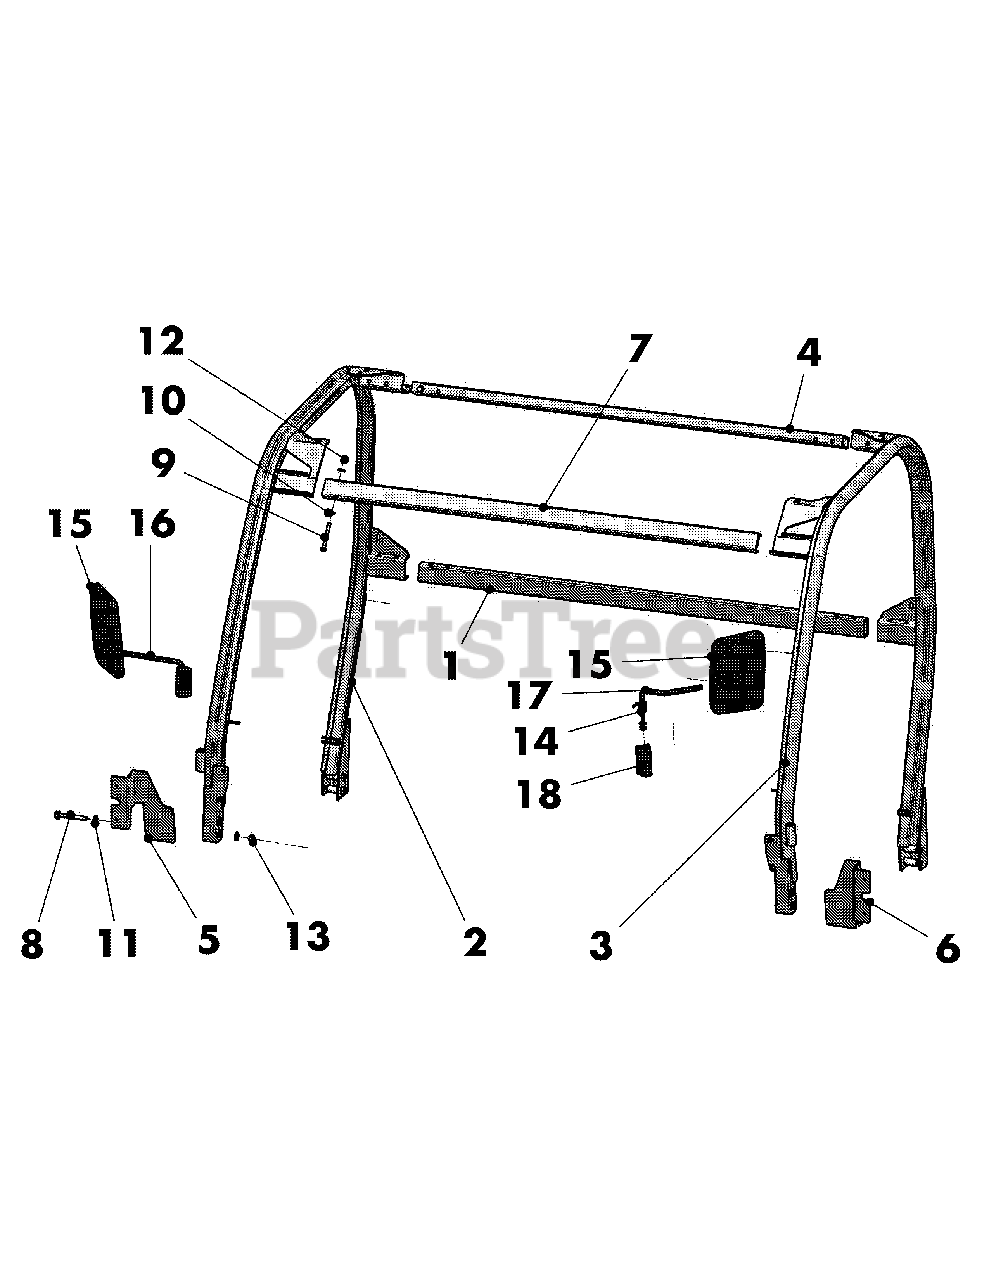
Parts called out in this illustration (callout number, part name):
1	Cross Tube - Rear
2	Side Element - RH
3	Side Element - LH
5	Console - Flasher RH
6	Console - Flasher LH
7	Cross Tube - Front
14	Pressure Spring
15	Mirror
16	mirror support right
17	mirror support left
